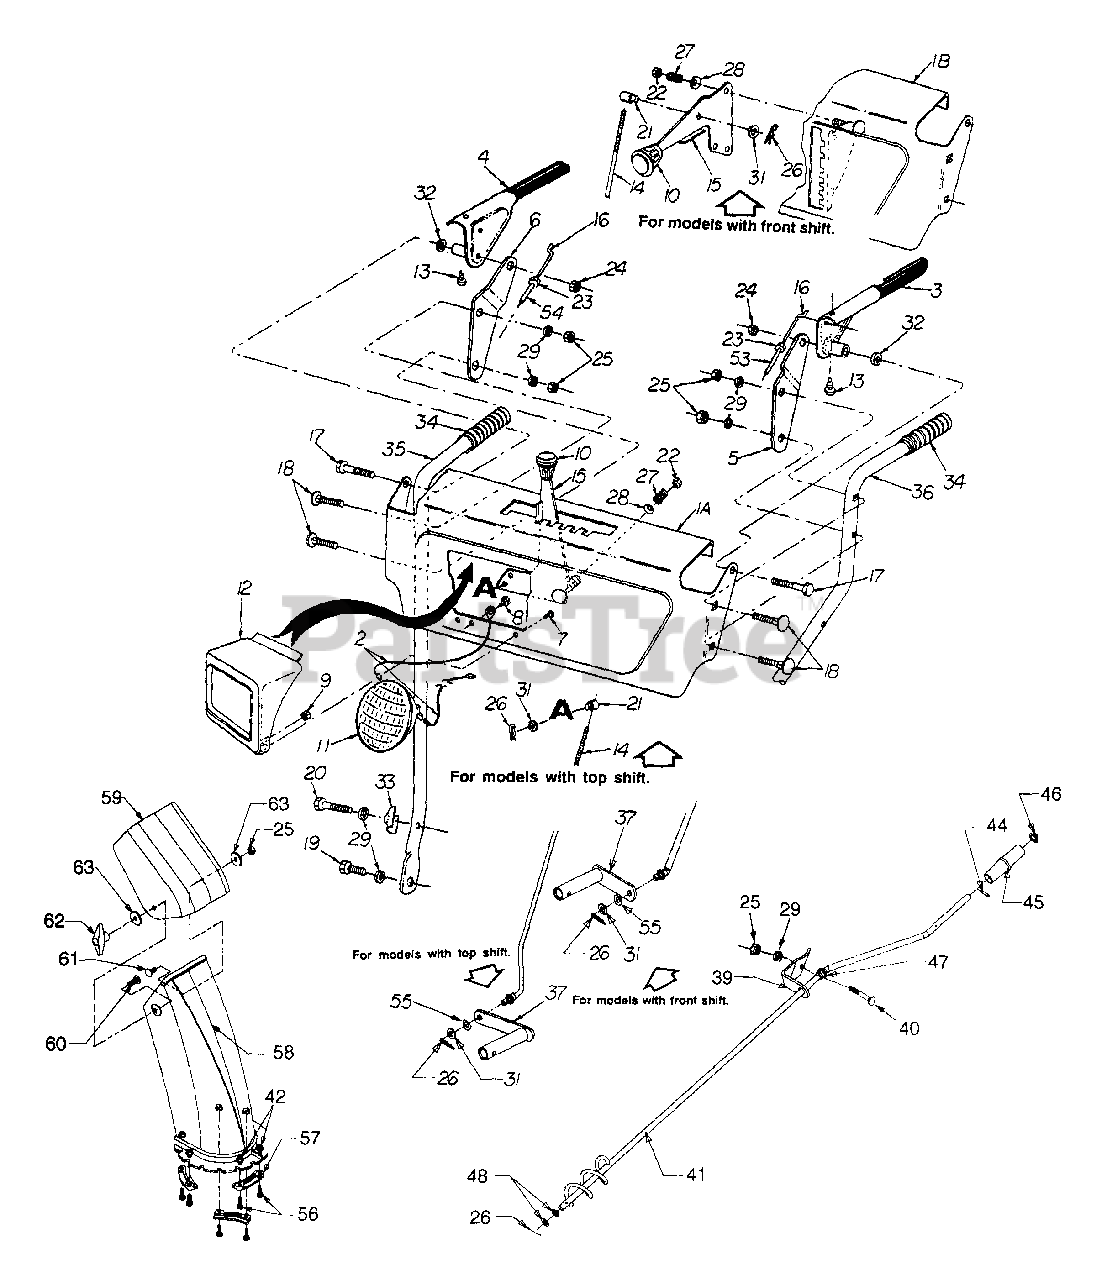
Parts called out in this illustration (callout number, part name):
3	Clutch Lever LH
4	Clutch Lever RH
8	Hex B-Tap Scr. 1/4-28 x .25" Lg.
9	Self Threading Nut .25
10	Ball Knob
11	Sealed Beam 18 Watt
12	Headlight Bezel
13	Rubber Bumper
14	Shift Rod
15	Shift Handle
16	"Z" Fitting
17	Hex Scr. 5/16-18 x 2.00
18	Carriage Bolt 5/16-18 x 1.50
19	Hex Bolt 5/16-18 x .75" Lg.
20	Hex Screw 5/16-18 x 1.75" Lg.
21	Adjustment Ferrule
22	Hex Nut 3/8-24
23	Hex Nut 10-24
24	Hex L-Nut 5/16-18
25	Hex Nut 5/16-18
26	Int. Cotter Pin 5/16 Dia.
27	Compression Spring .38 ID x .88 Lg.
28	Bell-Wash. .400 ID x .88 OD x .06
29	L-Wash. 5/16 ID
31	Flat Washer .34 ID x .63 OD
32	Spacer
33	Handle Tab
41	Chute Crank Ass'y.
42	Hex Flange Nut 1/4-20
44	Roll Pin .125 Dia. x .62
45	Knob - Chute Crank
46	Cap Speed Nut 3/8" Rod
47	Plastic Bushing
48	Flat Washer .385 ID x .62 OD x .06
53	Auger Clutch Cable (w/"Z" Fitting)
54	Drive Clutch Cable (w/"Z" Fitting)
55	Spring Wash. .317" I.D. x .625" O.D.
56	Hex Bolt 1/4-20 x .75" Lg. (Gr. 5)
57	Chute Keeper
58	Lower Chute
59	Upper Chute
60	Carriage Bolt 5/16-18 x 1" Lg.
61	Carriage Bolt 5/16-18 x .75" Lg.
63	Fl-Wash. .34" I.D. x 1.125" O.D.
